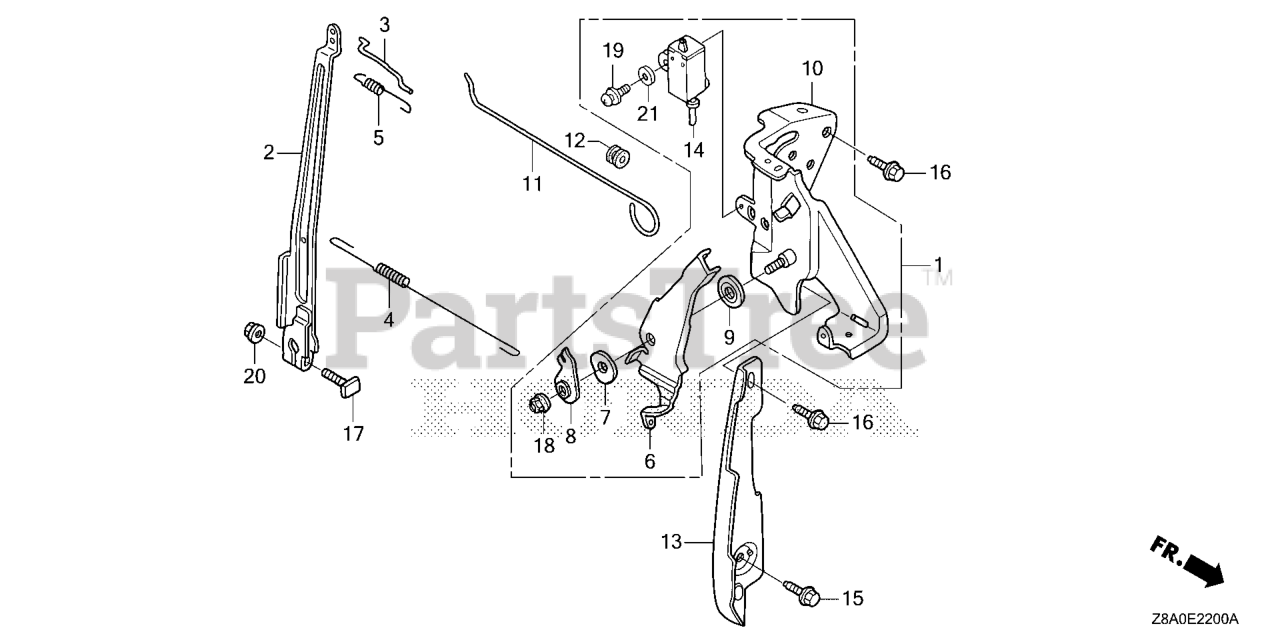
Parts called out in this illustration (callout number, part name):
1	CONTROL ASSY.
2	ARM, GOVERNOR
3	ROD, GOVERNOR
4	SPRING, GOVERNOR
5	SPRING, THROTTLE RETURN
6	LEVER, CONTROL
7	SPRING, LEVER
8	WASHER, CONTROL LEVER
9	SPACER, CONTROL LEVER
10	BASE, CONTROL
11	ROD, CHOKE CONTROL
12	GROMMET, CHOKE ROD
13	PLATE, SIDE
14	SWITCH ASSY., ENGINE STOP (N.O)
15	BOLT, FLANGE (6X12) (CT200)
16	BOLT, FLANGE (6X14)
17	BOLT, GOVERNOR ARM
18	NUT, SELF-LOCK (6MM)
19	SCREW-WASHER (4X12)
20	NUT, FLANGE (6MM)
21	WASHER, PLAIN (4MM)
